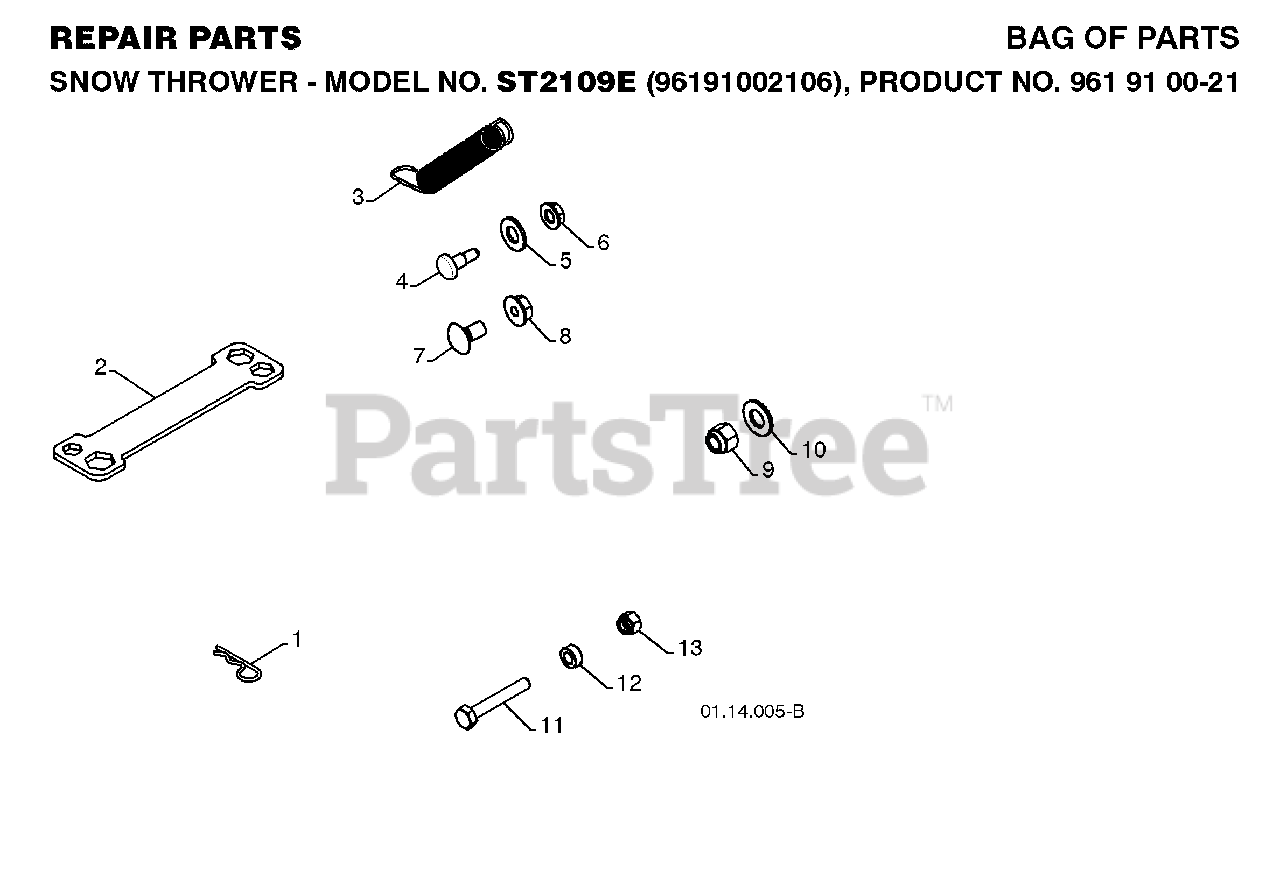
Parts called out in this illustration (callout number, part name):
1	SPRING RETAINER
2	RP WRENCH, SNOWTHROWER
4	BOLT, SHOULDER
5	WASHER, NYLON FRICTION
6	NUT.HEX.FLANGE.1/4
7	BOLT
8	NUT, LOCK 5/16-18
9	NUT
11	BOLT, SHEAR
13	LOCKNUT
